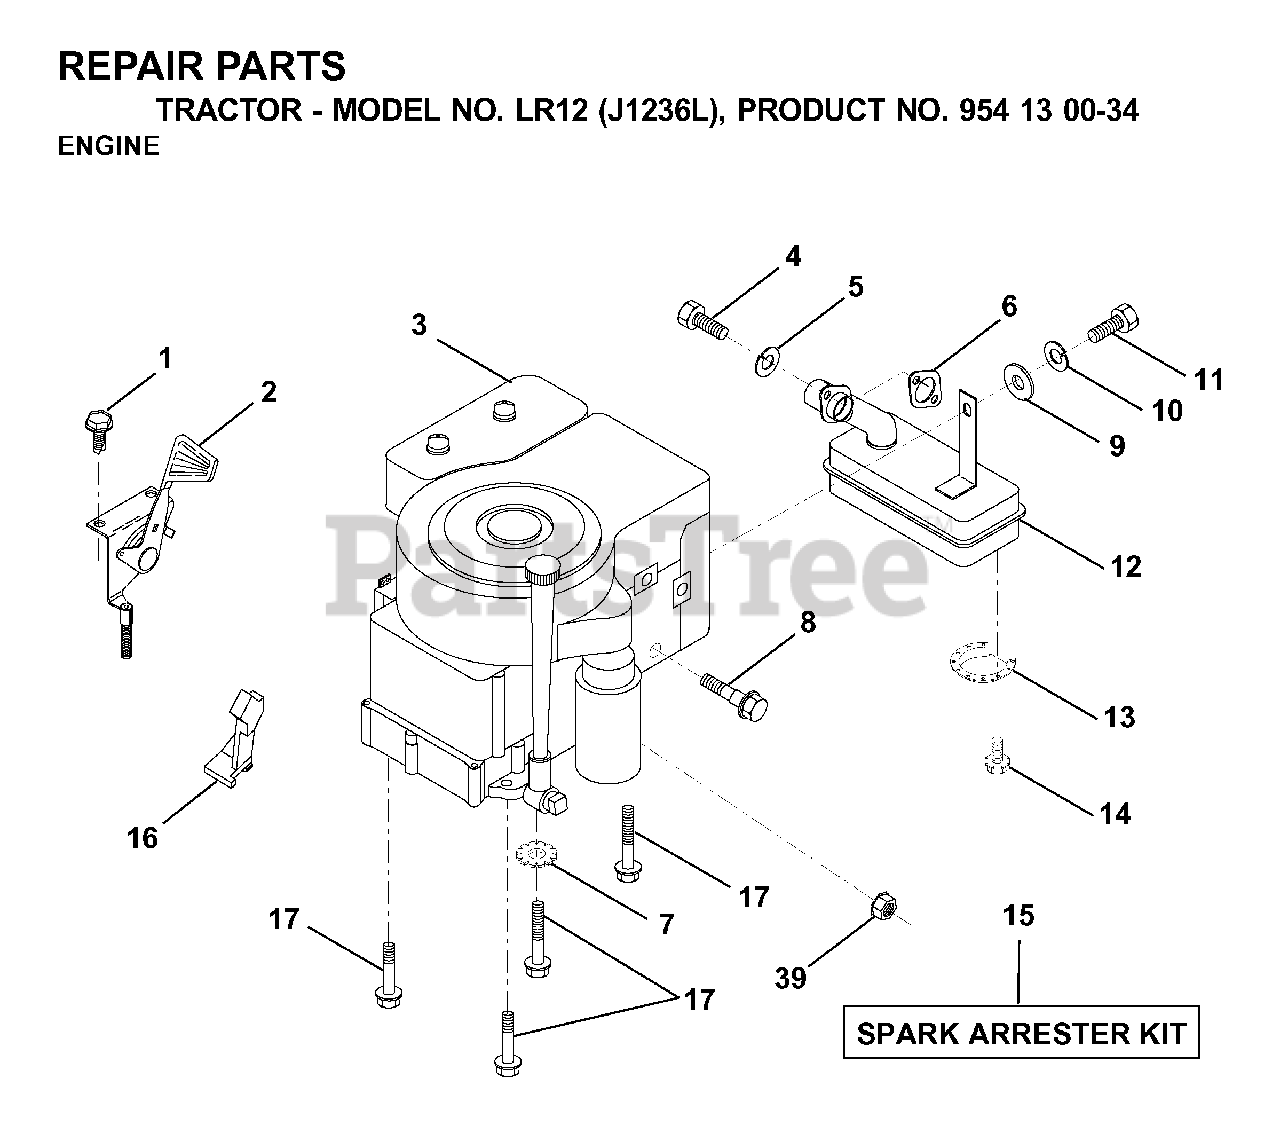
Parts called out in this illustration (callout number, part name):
1	SCREW LT
2	THROTTLE CONTROL
4	SCREW
5	LOCKWASHER
6	REPL BY 532 27 22-93
7	LOCKWASHER
9	WASHER
10	LOCKWASHER
13	DEFL MUFFLER LTV
14	SCREW
15	ARRESTER SPARK (OPTIONAL)
16	STOP THROTTLE
17	SCREW LT
39	NUT FLANGE 1/4-20 STARTER NUT
